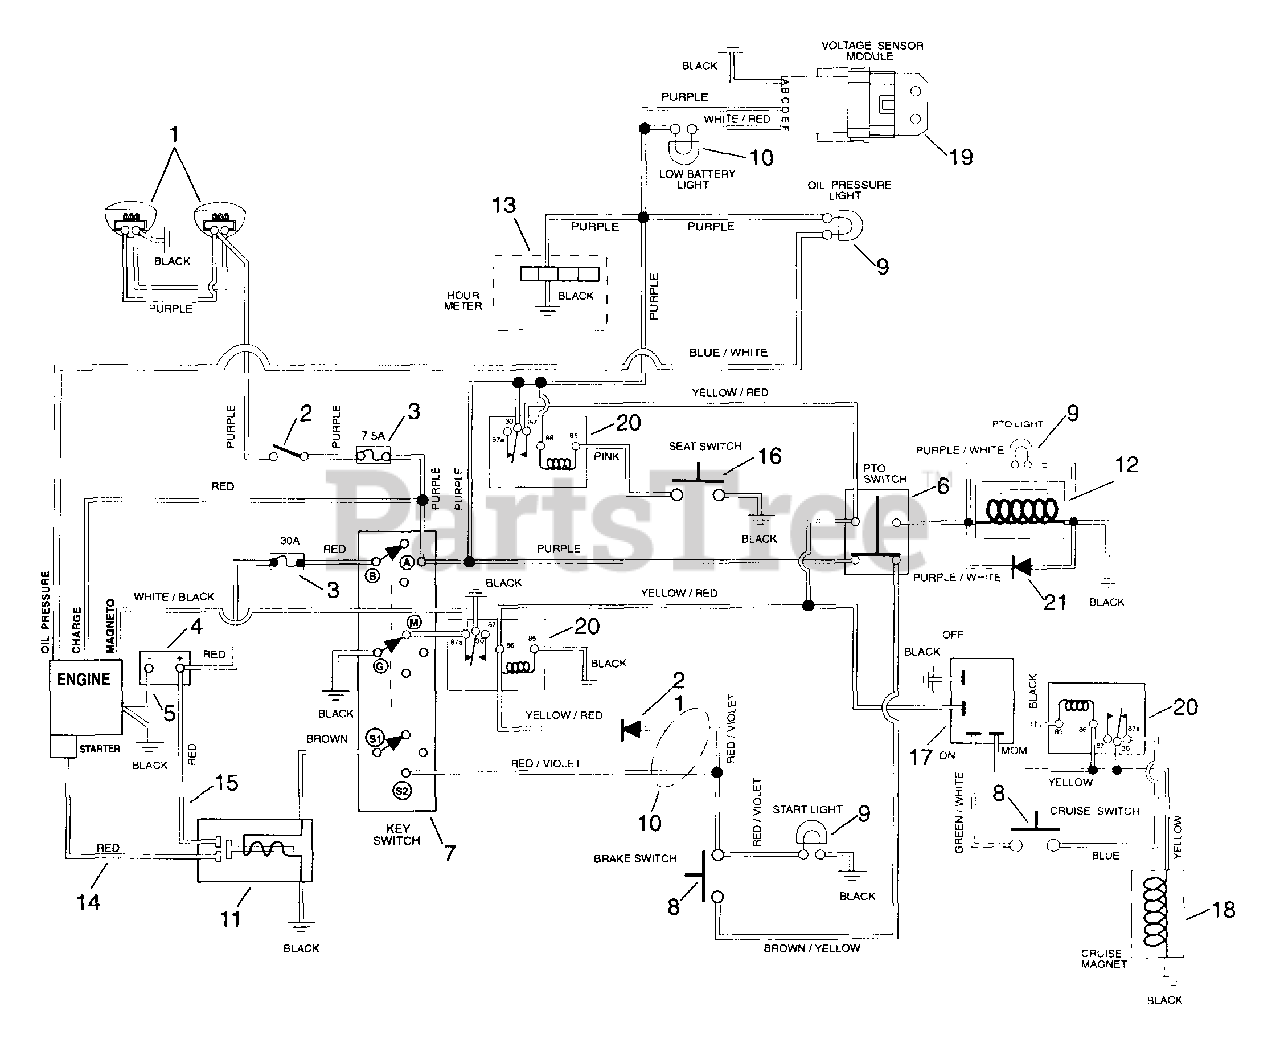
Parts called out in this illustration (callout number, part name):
1	Headlights-Right Hand
1	Headlights-Left Hand
2	Switch-Light
4	Battery W/Tube
5	Ground Cable
6	PTO Knob/Switch Assembly
7	Key Switch
8	Switch-Single Pole N.O.
10	Wire Harness-1540H Kohler
10	Wire Harness-1548H Kohler
11	Solenoid
12	Electric Clutch/Brake
12	Clutch-Electric-Warner
13	Hourmeter Kit-Sierra
14	Starter Cable 22"
15	Starter Cable 6.75"
16	Switch-Seat
17	Switch-Cruise
19	Module-Voltage Sensor
20	Relay
21	Molded Diode Plug-Clear Lamp
